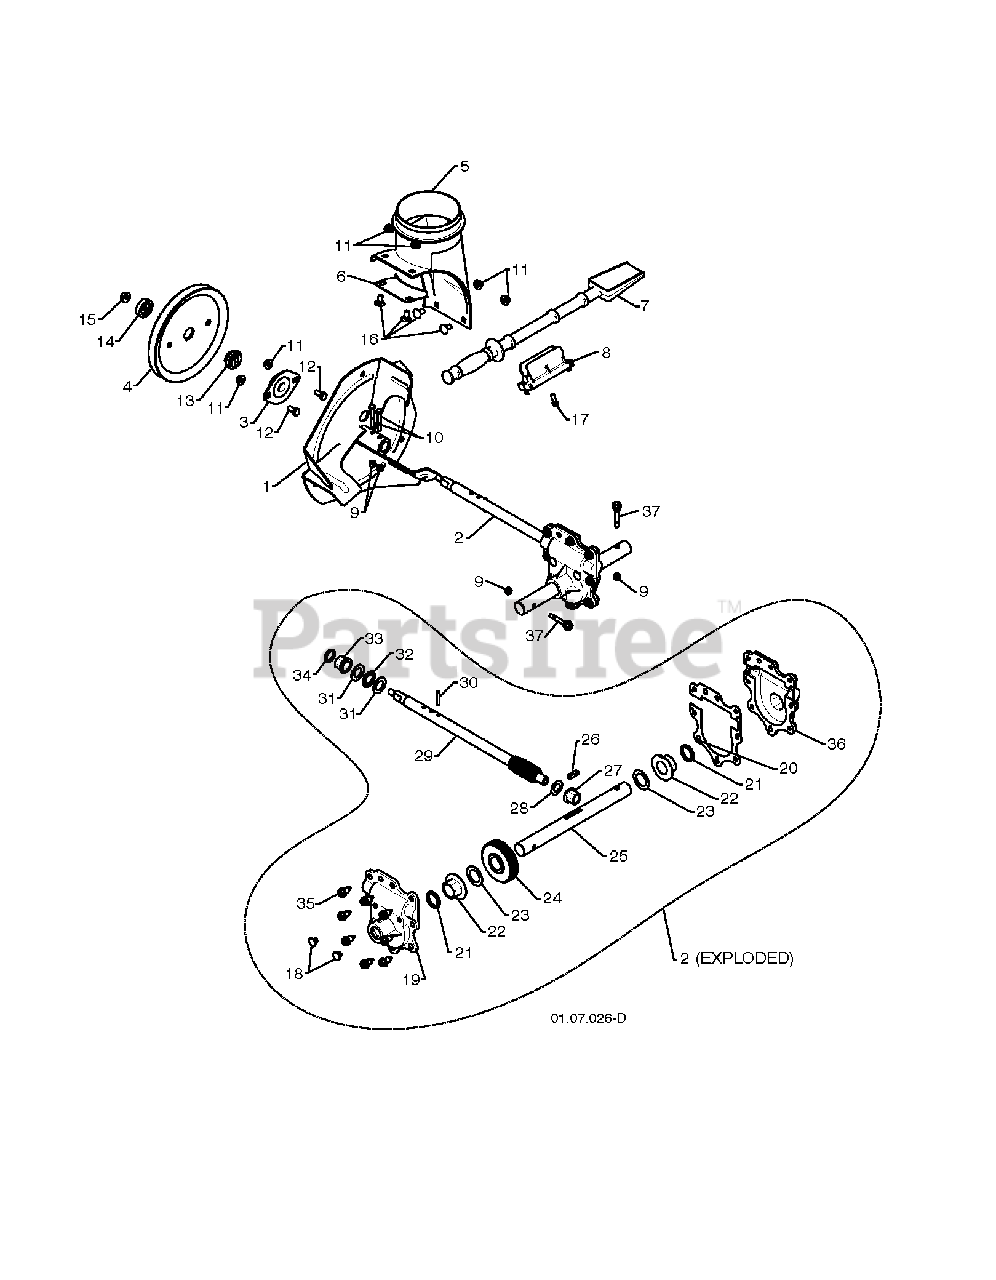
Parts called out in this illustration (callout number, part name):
1	IMPELLER.WELDMENT.PNT
2	GEARBOX.ASM.AUGER.D-SHAFT
3	BEARING FLANGE
4	PULLEY.FLANGE.IMPELLER
5	BASE DISCHARGE CHUTE
6	BRACKET.CORNER.DISCHARGE
7	CLEAN OUT TOOL
8	CLIP.CLEANOUT.TOOL
9	LOCKNUT
10	SCREW.HEX.HD1/4-20X
11	NUTNYLOK.FLRANGE.5/16-18
12	BOLT, HEX HEAD 5/16-18
13	HUB.IMP.PULLEY.D-SHAFT
14	SLEEVE.IMP.PULLEY.D-SHAFT
15	NUT LOCK FLG 3/8-16 UNC
16	BOLT.CARRIAGE.5/16-18X
17	SCREW.HWH.13-16-5.8.BZP
18	CASE PLUG
19	GEAR.BOX.COVER.RIGHT.SIDE
20	GASKET.GEAR.BOX
21	OIL SEAL
22	FLANGE BUSHING-1"
23	WASHER TRUST 1"
24	WORM GEAR
25	AUGER SHAFT
26	KEY, SQUARE 1/4 X .875
27	FLANGE BUSHING-5/8
28	WASHER, THRUST 5/8
29	SHAFT.IMPELLER.D-SHAFT
30	PIN, ROLL 3/16 X 1-1/8
31	WASHER, THRUST 3/4
32	BEARING TRUST 3/4
33	BUSHING, FLANGE 3/4
35	HEX SCREW-5/16 X 3/4
36	GEAR.BOX.COVER.LEFT.SIDE
37	BOLT, SHOULDER SHEAR
